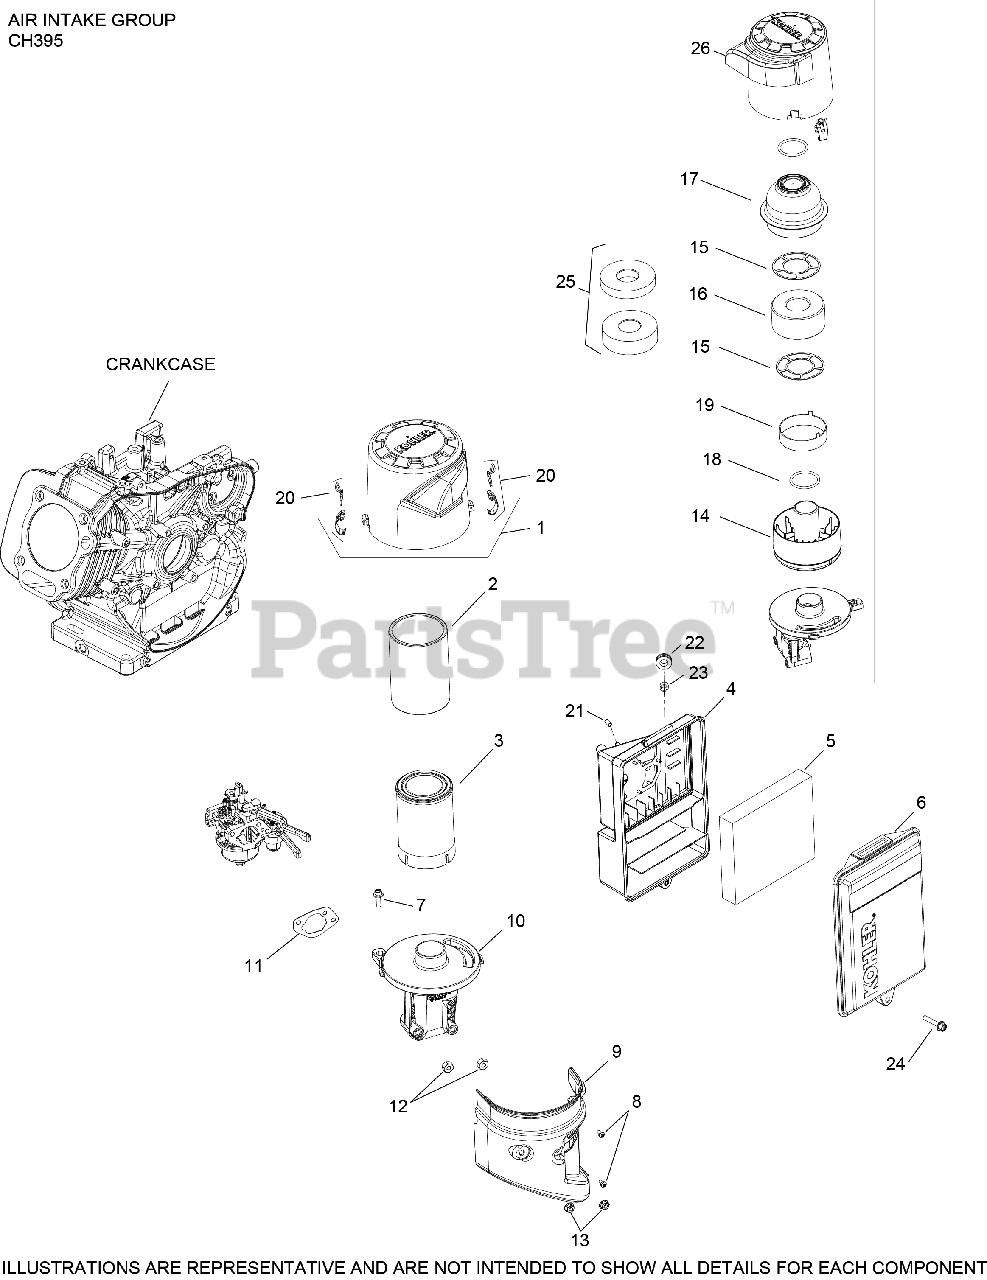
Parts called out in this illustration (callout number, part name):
1	COVER, AIR CLEANR ASSEMBLY
2	ELEMENT, PRE-CLEANER
3	ELEMENT, AIR FILTER
8	SCREW,COVR TO BLWR HOUSING
9	COVER, A/C BASE CH395
10	BASE ASSY,AIR CLEANER CYCLONIC
11	GASKET, AIR CLEANER
12	NUT, HEX (M6 THREAD, M8 BODY)
20	KIT, LATCH CLIP
